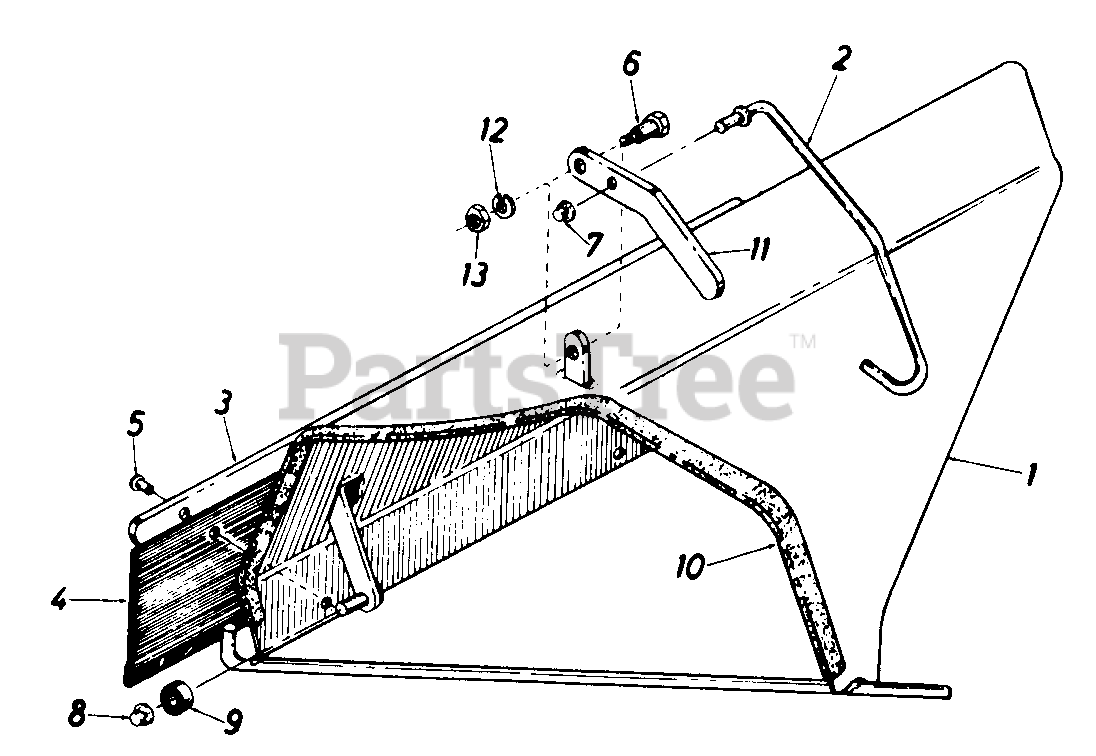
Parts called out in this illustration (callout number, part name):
1	DEFLECTOR ASSY
2	HOOK ASSY
3	STRIP-RETAINING
5	RIVET-POP
6	SCREW-SHLD
9	ROLLER-PLASTIC
10	STRIP-TRIM-12IN
11	LATCH-ARM
12	LOCK WASHER 1/4 DIA
13	NUT-HEX 1/4-20
